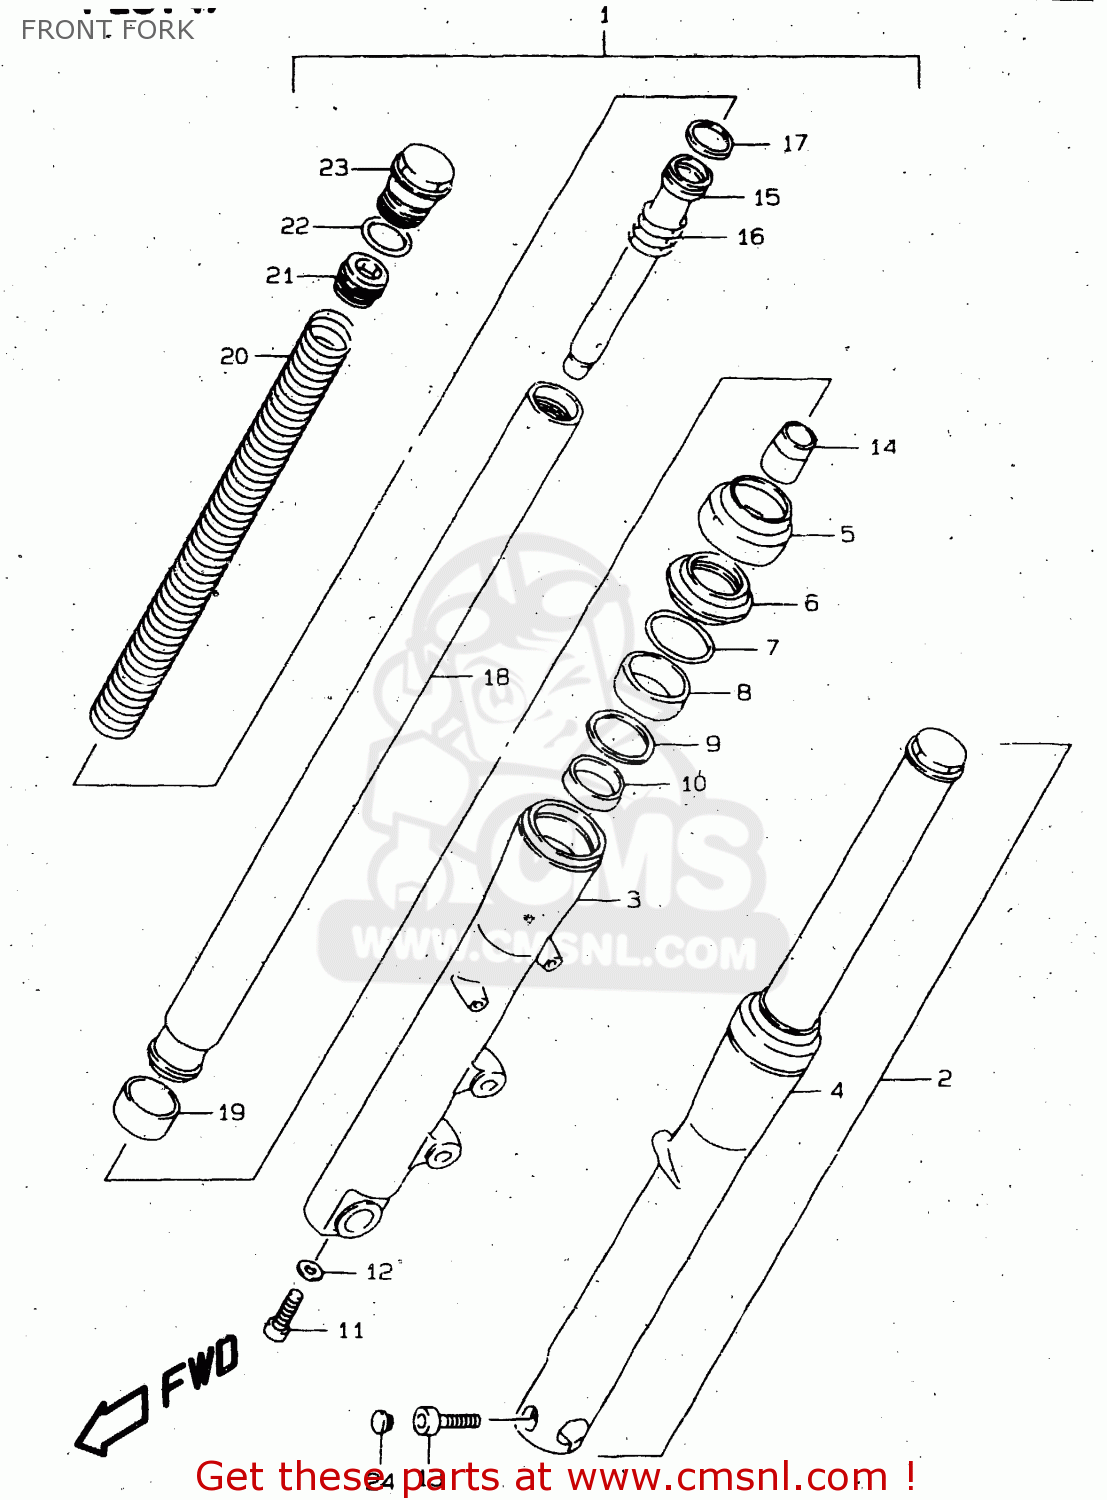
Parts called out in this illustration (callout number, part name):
1	DAMPER ASSY,FR FORK,R
2	DAMPER ASSY,FR FORK,L
3	TUBE,OUTER,R
4	TUBE,OUTER,L
5	COVER,CASE
6	DUST SEAL
7	CIRCLIP,FORK OIL SEAL
8	SEAL,OIL
9	SPACER,SEAL
10	BUSH,GUIDE
11	BOLT(8X27)
12	GASKET (NAS)
13	BOLT
14	PIECE,OIL LOCK
15	CYLINDER
16	SPRING,REBOUND
17	RING,PISTON
18	TUBE,INNER
19	BUSH,SLIDE
20	SPRING,FR FORK
21	BOLT,FORK INNER
22	O RING
23	BOLT
24	CAP(OD:14.5)
